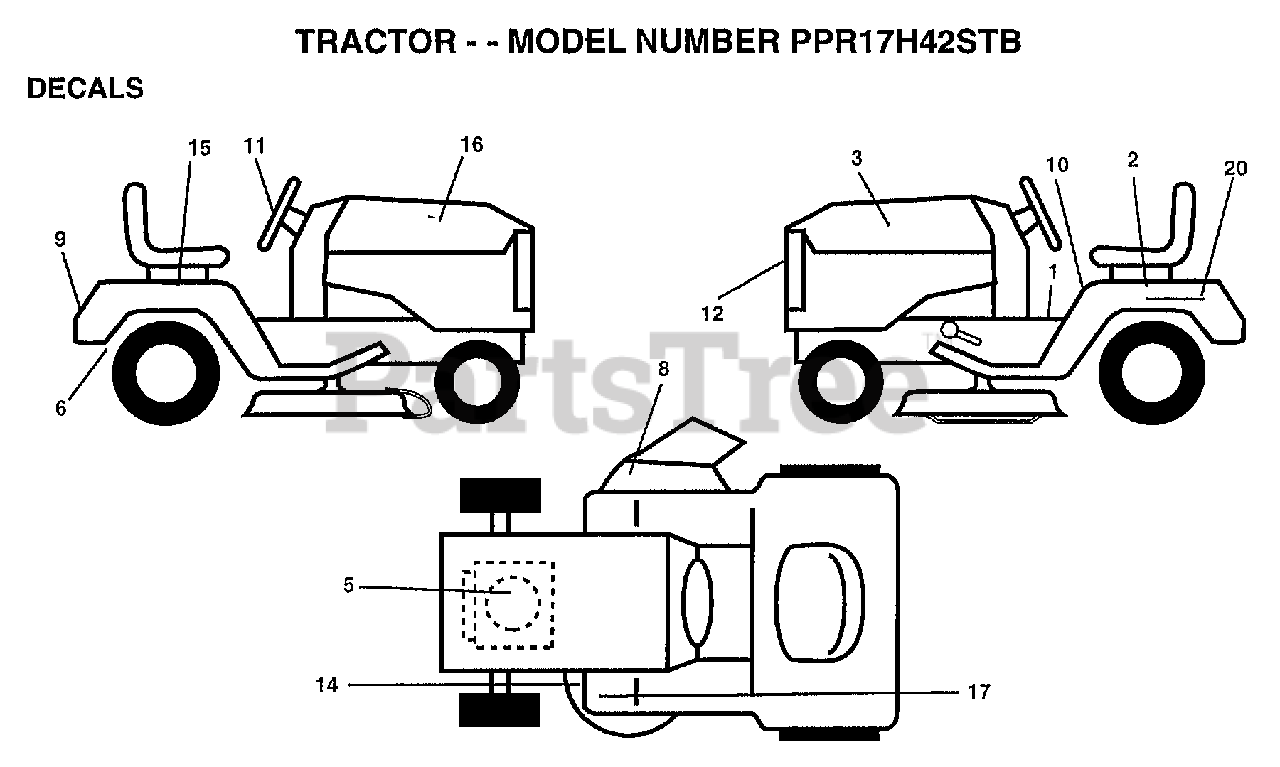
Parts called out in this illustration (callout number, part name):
1	DECAL SADDLE OPER
2	DECAL.FENDER.SD.AUTO
3	DECAL.HOOD.LH
5	DECAL, HP ENGINE
6	DECAL BY PASS LT HYDRO
8	"DECAL, WARNING"
9	DECAL.FENDER.LOGO
10	DECAL.CAUT.ENG/FR
11	DECAL.INS.WHL.STRG
12	DECAL.GRILLE.
14	"DECAL-SCHEM,BELT"
15	DECAL.FENDER.SD.RH.
16	DECAL.HOOD.RH
17	DECAL T
20	DECAL.BATRY.3-3908
